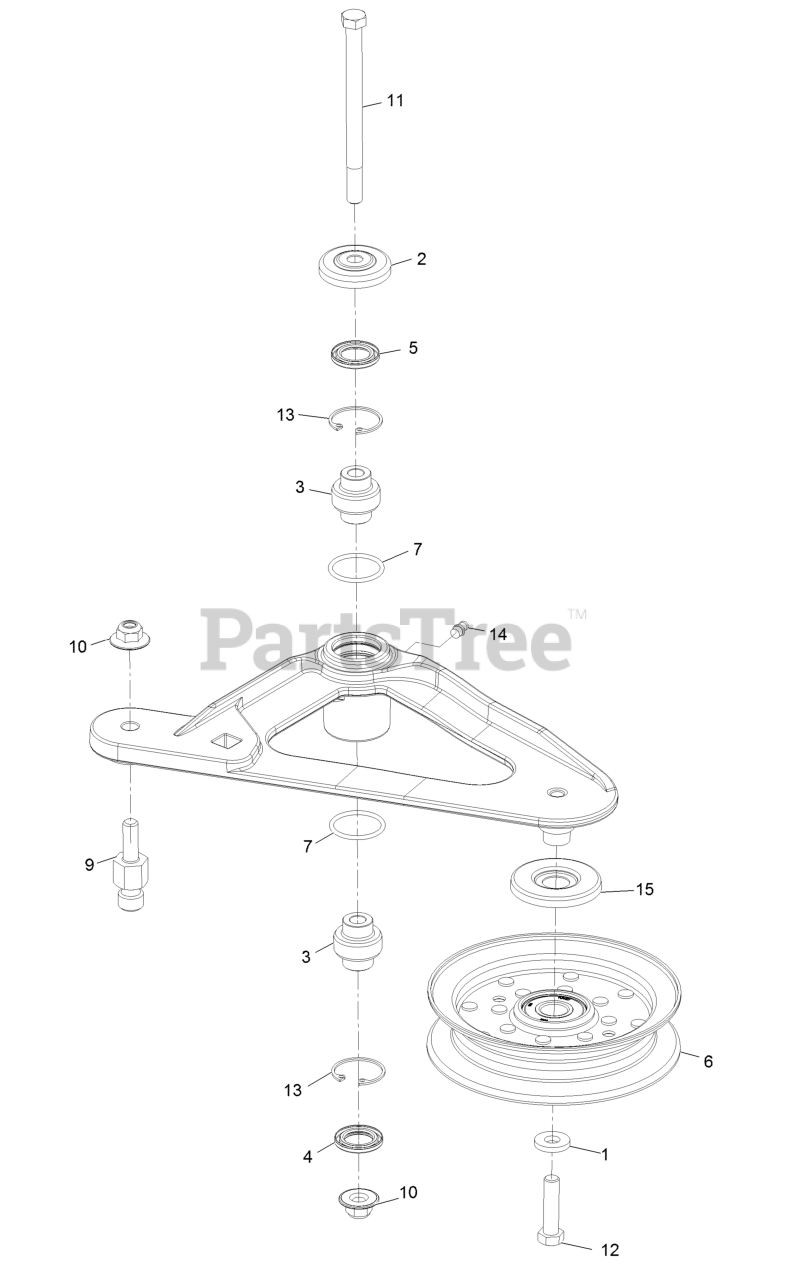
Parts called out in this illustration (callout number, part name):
2	Guard-Top
3	Bearing-Spherical
4	Seal-Lip, Double
5	Seal-Lip, Single
6	Idler-Pulley, Flat
9	Pin-Spring, Anchor
10	Nut-Flange, NI
11	Screw-Shoulder, HH
12	Screw-HH
13	Ring-Snap
14	Fitting-Grease
15	Shield-Guard, Dust
